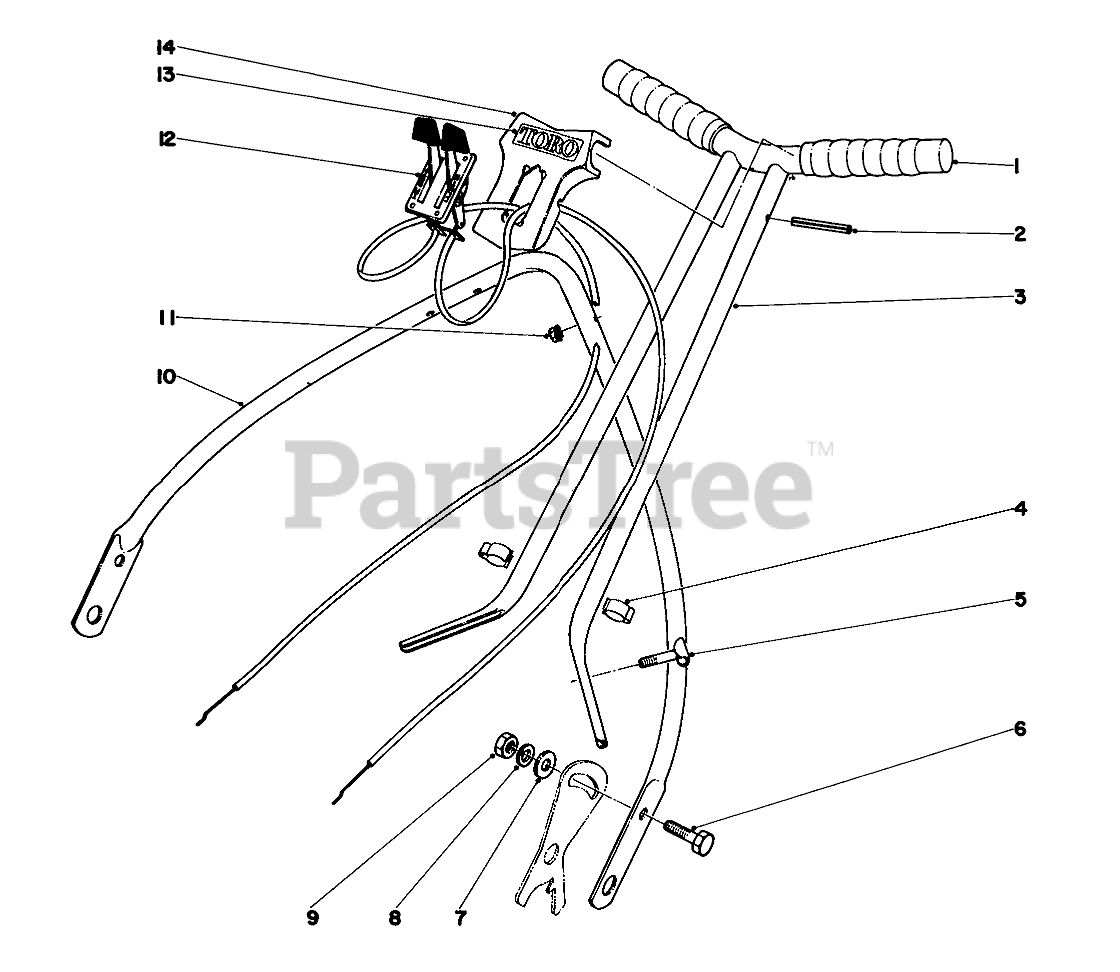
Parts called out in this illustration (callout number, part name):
1	Handle Clip
2	PIN-ROLL
3	Upper Handle
4	CONTROL WIRE CLIP
6	SCREW-HH
7	WASHER-PLAIN
8	WASHER-LOCK
9	NUT-HEX
10	Lower Handle
11	NUT-KEPS
12	Control Assembly
13	Decal
14	Cover Plate
